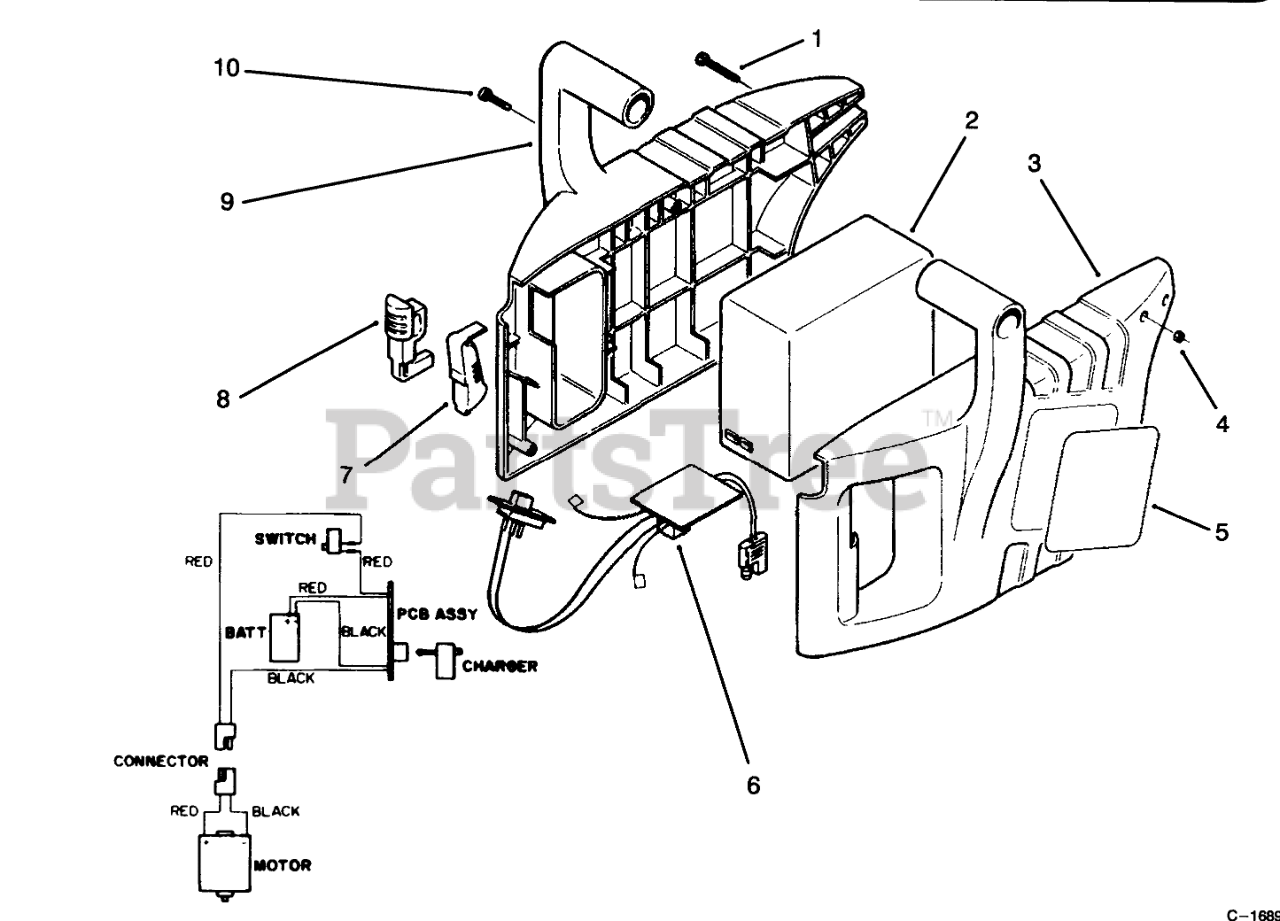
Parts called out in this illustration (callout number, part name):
1	SCREW-PPH
2	BATTERY
3	RH BATTERY CASE/HNDL
4	NUT-HEX
5	DECAL - 7" TRIM
6	ASSY-PCB
7	TRIGGER
8	TRIGGER LOCK
9	LH BATTERY CASE/HNDL
10	Screw
